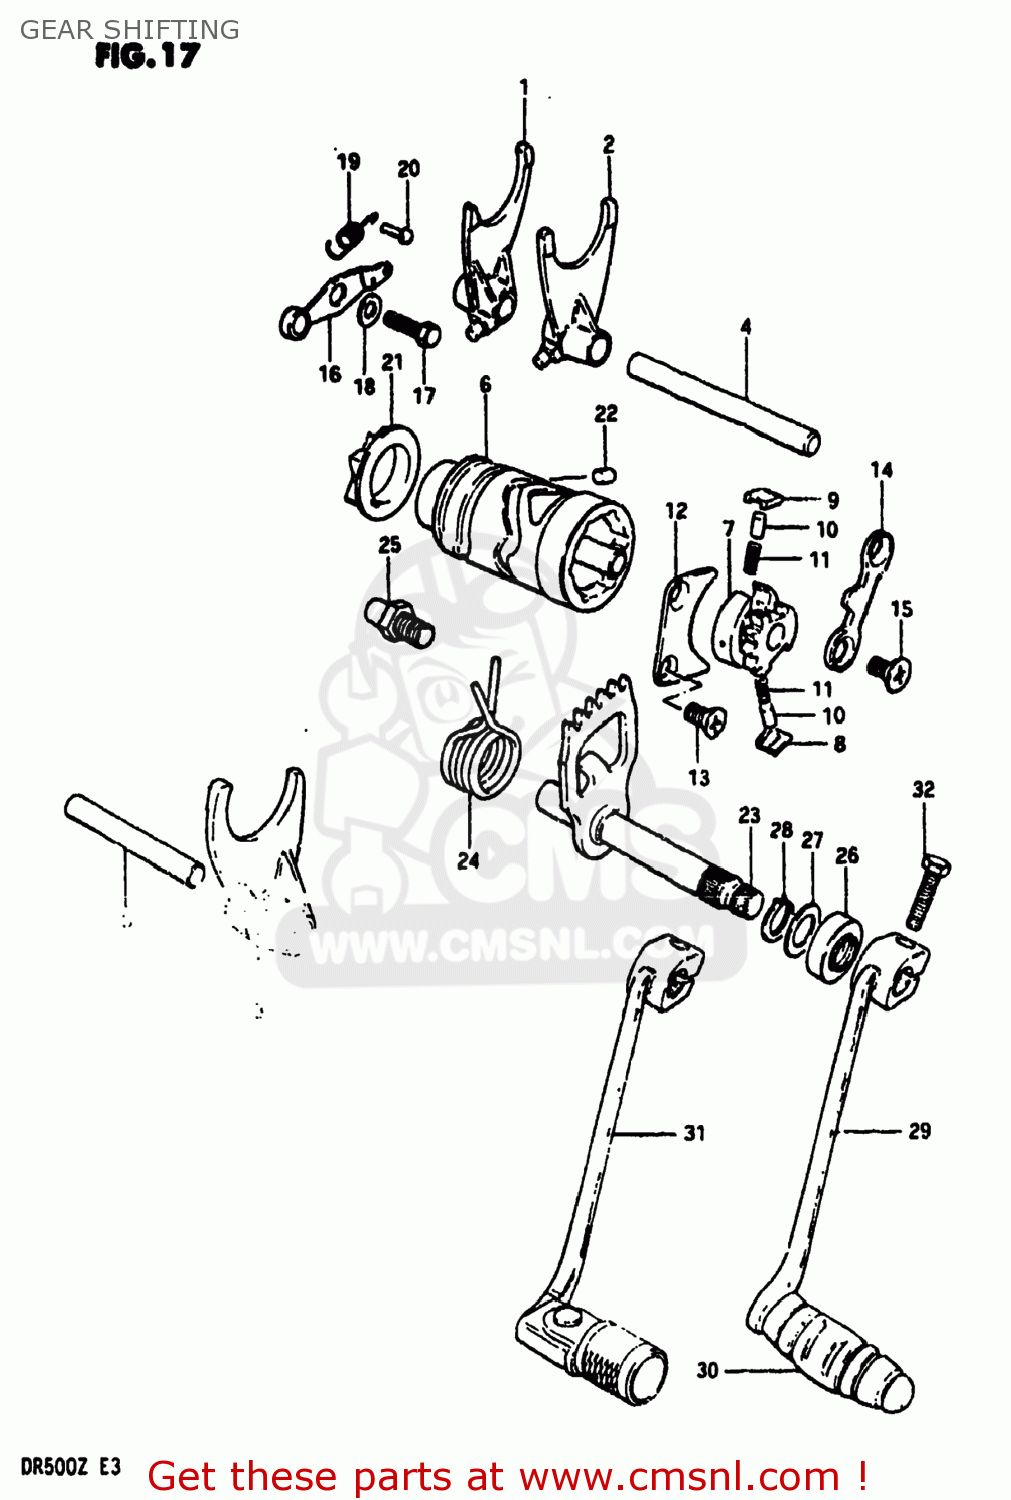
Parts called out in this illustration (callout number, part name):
1	FORK,GEAR SHIFT NO.1
2	FORK,GEAR SHIFT NO.2
3	FORK,GEAR SHIFT NO.3
4	SHAFT,GEAR SHIFT FORK
5	SHAFT,GEAR SHIFT FORK
6	CAM,GEAR SHIFT
7	SHIFTER,GEAR SHIFT CAM
8	PAWL,GEAR SHIFT NO.1
9	PAWL,GEAR SHIFT NO.2
10	PIN(5X8)
11	SPRING
12	LIFTER,GEAR SHIFT PAWL
13	SCREW
14	GUIDE,GEAR SHIFT CAM
15	SCREW
16	STOPPER,GEAR SHIFT CAM
17	BOLT
18	WASHER
19	SPRING
20	RIVET
21	PLATE,SHIFT CAM STOPPER
22	PIN 4X6
23	SHAFT,GEAR SHIFT
24	SPRING
25	STOPPER,GEAR SHIFT CAM
26	OIL SEAL
27	WASHER
28	CIRCLIP
29	LEVER ASSEMBLY,GEAR SHIFTING
30	RUBBER,GEAR SHIFT PEDAL
31	LEVER ASSEMBLY,GEAR SHIFTING
32	BOLT
